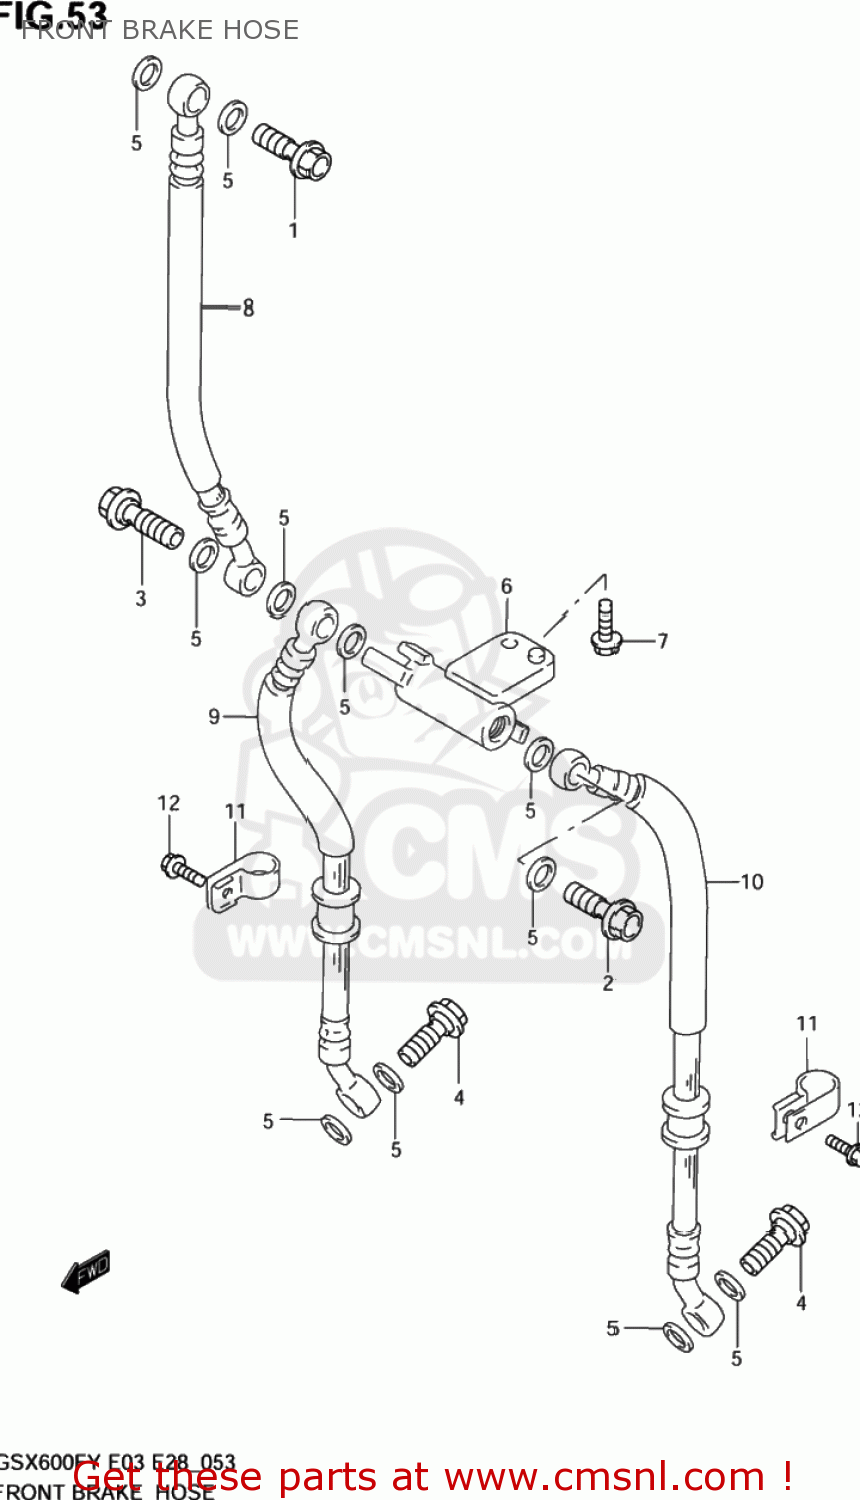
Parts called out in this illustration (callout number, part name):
1	BOLT UNION
2	BOLT UNION
3	BOLT UNION
4	BOLT UNION
5	WASHER(10X15X1.5)
6	JOINT,BRAKE HOSE
7	BOLT
8	HOSE COMP,FRONT BRAKE NO
9	HOSE COMP,FRONT BRAKE
10	HOSE COMP,FRONT BRAKE
11	CLAMP,FR BRAKE HOSE NO.2
12	BOLT
